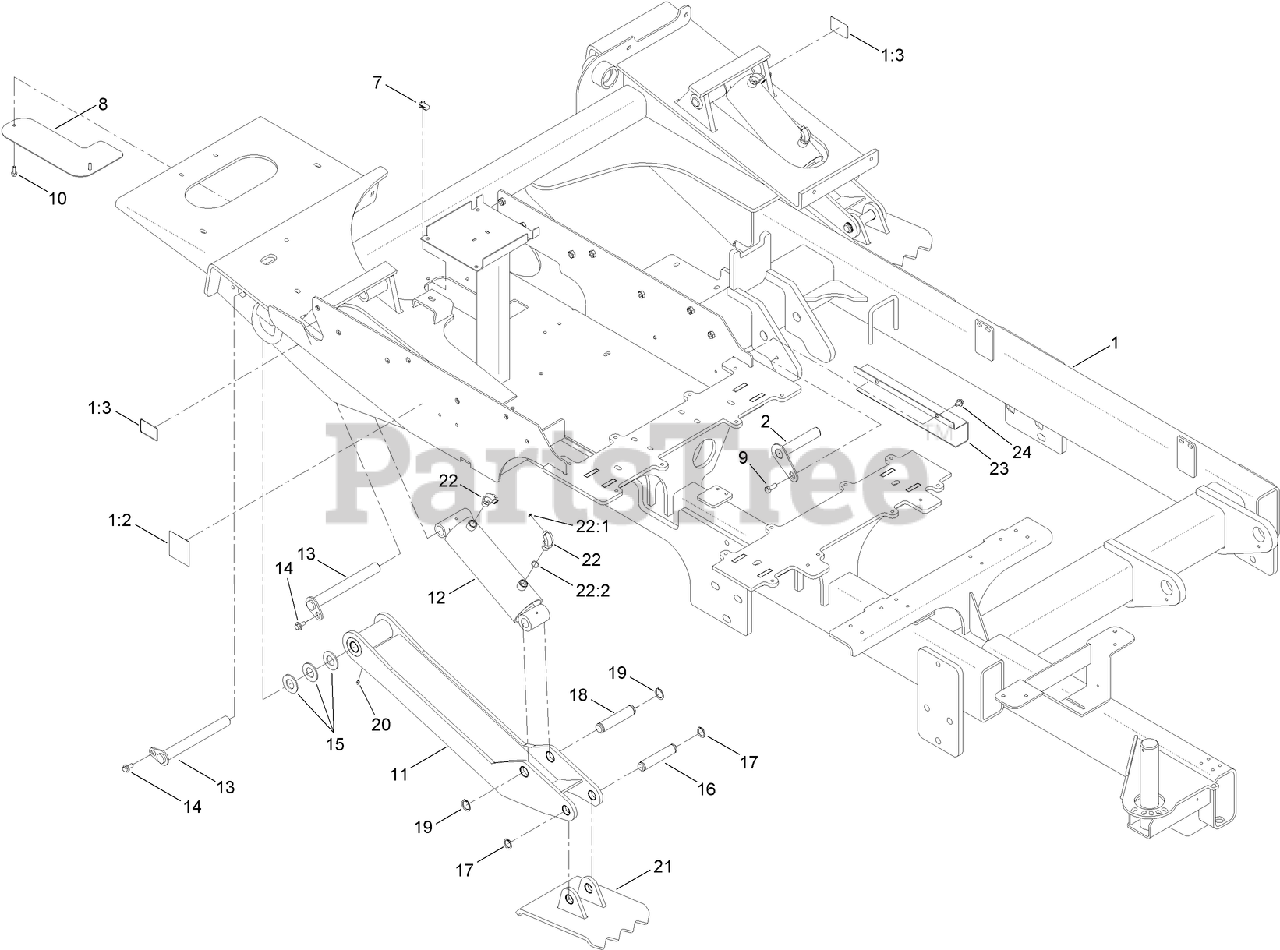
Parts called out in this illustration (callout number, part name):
1	FRAME ASM
1:2	DECAL-WARNING, CRUSHING
1:3	DECAL-LIFT/TIE DOWN
2	PIN-DIPPER CYLINDER TO BOOM
8	COVER-VALVE, 5 SECTION
9	SCREW-HH
10	SCREW-HHF
11	STABILIZER
12	HYD CYLINDER ASM
13	PIN-W/FLAG
14	SCREW-HHF
15	WASHER-HARDENED
16	PIN (STABILIZER PAD END)
17	RING-RETAINING
18	PIN-STABILIZER (CYLINDER ROD END)
19	RING-RETAINING
20	FITTING-GREASE
21	FOOT-STABILIZER
22	FITTING-ELBOW 90
22:1	O-RING
22:2	O-RING
23	PLATE-GUARD, WIRE HARNESS
24	SCREW-HHF
